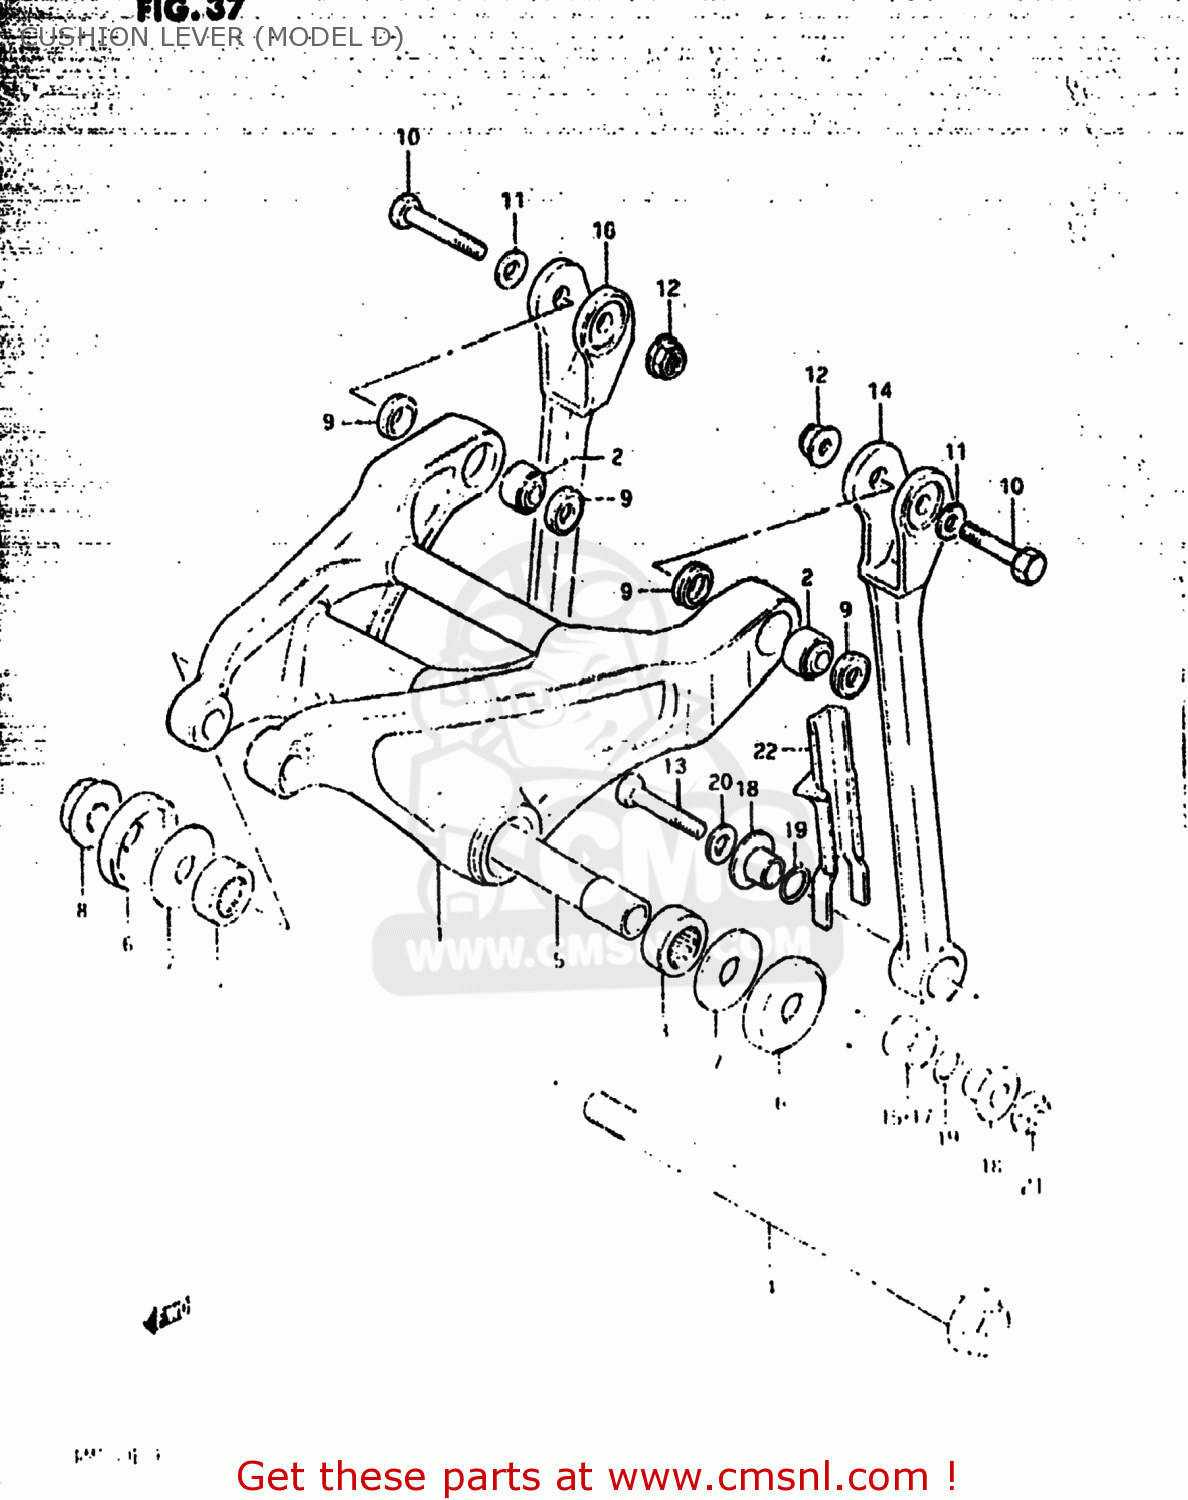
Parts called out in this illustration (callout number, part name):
1	LEVER SET,REAR CUSHION
2	BEARING(8X18X11)
3	BEARING(17X26X20)
4	SHAFT,REAR CUSHION LEVER
5	SPACER,REAR CUSHION LEVER
6	DUST SEAL
7	WASHER(12X35X2)
8	NUT 12MM
9	DUST SEAL,RR CUSHION LOD UPR
10	BOLT,REAR CUSHION LEVER
11	WASHER
12	NUT
13	BOLT,REAR CUSHION LEVER
14	LEVER SET,REAR CUSHION
15	BUSHING
16	LEVER SET,REAR CUSHION
17	BUSHING
18	SPACER,RR CUSHION ROD LWR
19	DUST SEAL,REAR CUSHION
20	WASHER
21	NUT
22	PROTECTOR,REAR CUSHION R
